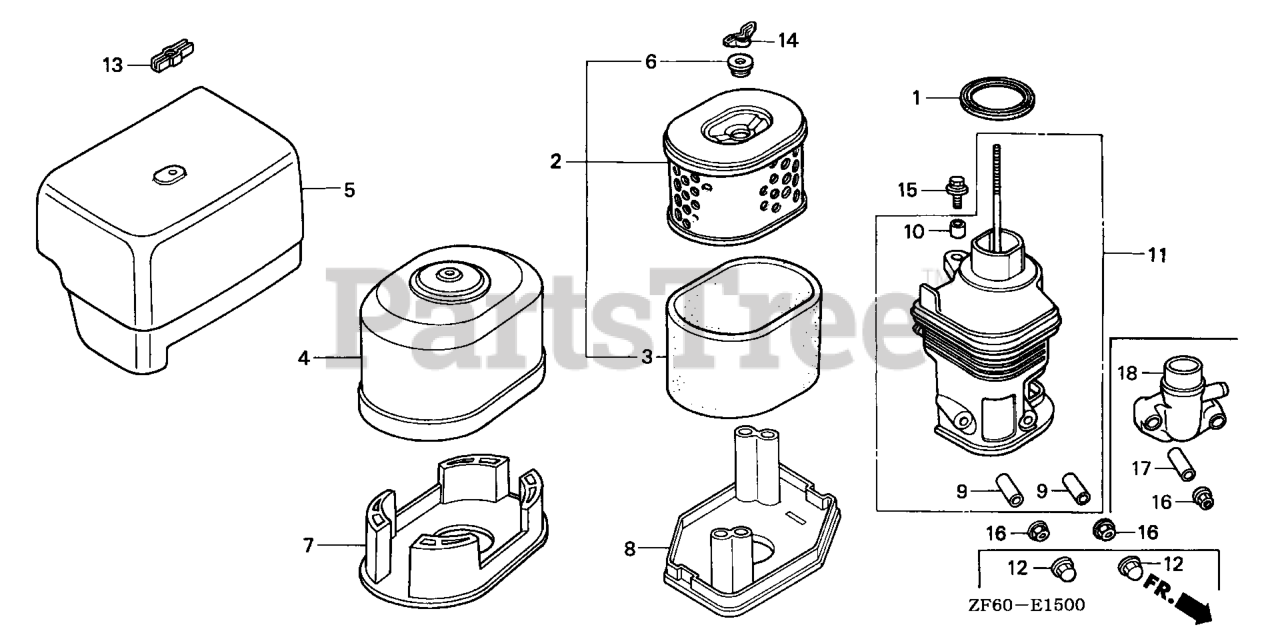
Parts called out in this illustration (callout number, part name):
1	GASKET, ELBOW
2	ELEMENT, AIR CLEANER
3	FILTER (OUTER)
5	COVER, AIR CLEANER
6	GROMMET, AIR CLEANER
8	NOSE, MUFFLER
9	COLLAR, AIR CLEANER
10	COLLAR B, AIR CLEANER
11	ELBOW, AIR CLEANER
12	NUT, CAP (6MM)
13	WINGNUT, AIR CLEANER COVER
13	WINGNUT (6MM)
14	WINGNUT, TOOL BOX SETTING
15	BOLT-WASHER (6X20)
16	NUT, FLANGE (6MM)
